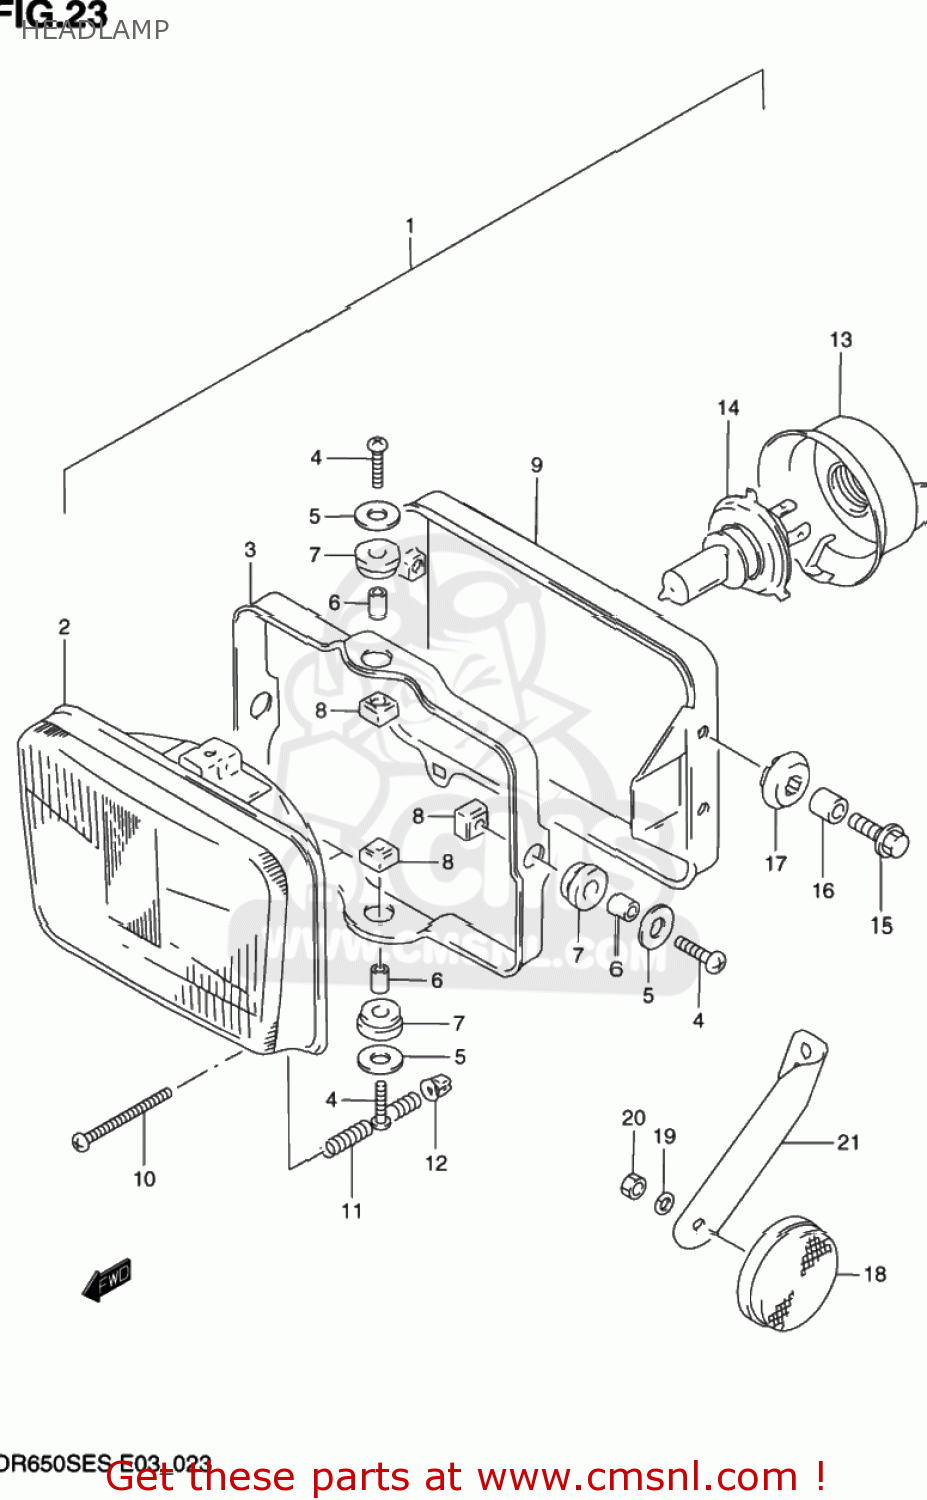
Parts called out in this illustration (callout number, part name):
1	HEADLAMP ASSEMBLY
2	UNIT ASSY
3	RING,MOUNTING
4	SCREW,HEADLAMP ADJUST
5	WASHER
6	SPACER
7	CUSHION
8	NUT
9	HOUSING
10	SCREW(4X45)
11	SPRING,ADJUSTING
12	NUT,ADJUSTING
13	COVER,SOCKET
14	BULB(12V60/55W,H4)
15	BOLT 6X20
16	SPACER (6.8X10X10)
17	CUSHION
18	REFLEX REFLECTOR ASSY,FR SIDE
19	LOCK WASHER
20	NUT
21	BRACKET,FR SIDE REFLECTOR,R
